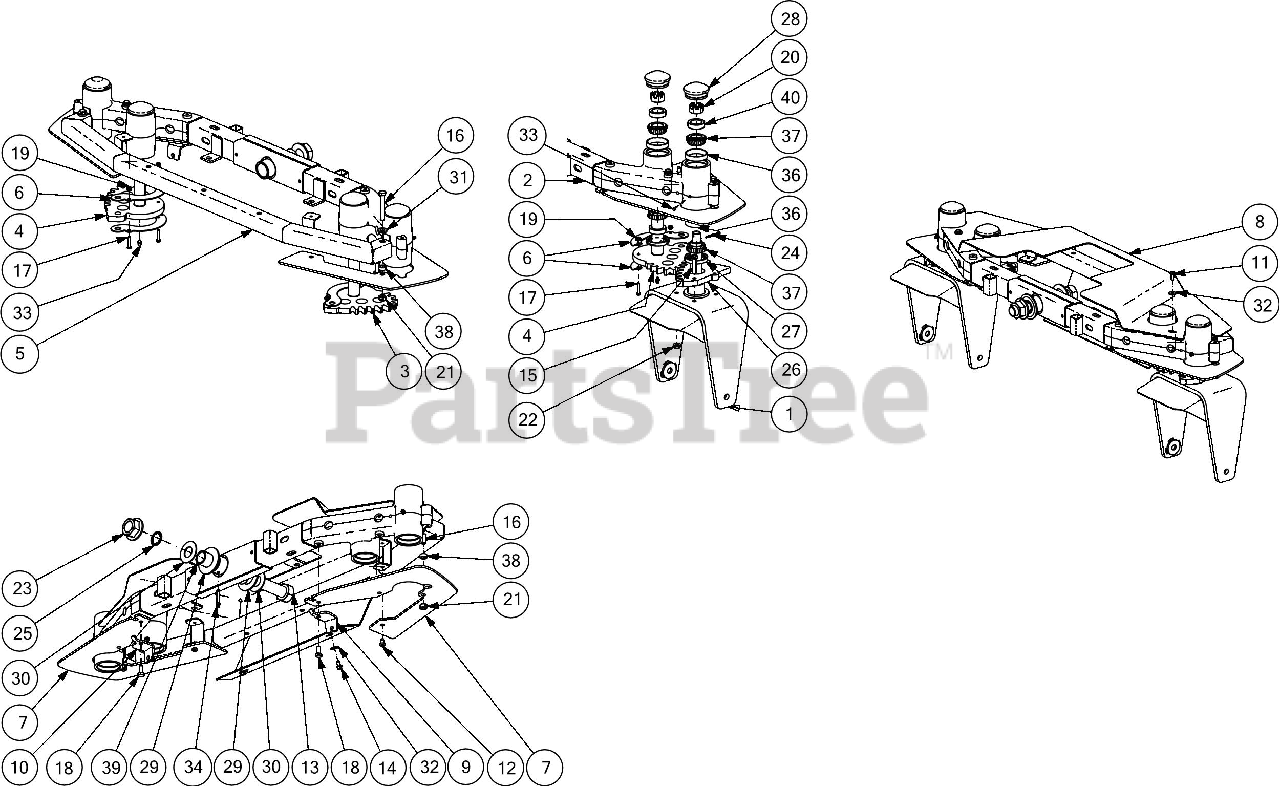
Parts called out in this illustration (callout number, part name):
1	TANK YOKE ASSEMBLY
2	AXLE ASSEMBLY
3	STEERING GEAR (LH)
4	STEERING GEAR (RH)
6	MOUNT BRACKET
7	GEAR PANEL COVER
9	CABLE MOUNT BRACKET (RH)
10	CABLE MOUNT BRACKET (LH)
11	SCREW 1/4-20 X .62 SPEC GR5
12	SCREW 1/4-20 X .5
13	SCREW 1-14 X 7.0 GR5
14	SCREW 1/4-20 X.500
15	SCREW 5/16-18 X 1.5 LG
16	HEX SCREW-3/8-16X2.5 GR5
17	SCREW #10-24 X 1.00 GR5.1
18	SCREW 5/16-18 X .750
20	HEX NUT CASTLE 3/4-16
23	HEX FLANGE NUT
24	COTTER PIN-5/32 DIA
25	RETAINING RING
26	STEERING GEAR YOKE
28	AXLE GREASE CAP
29	BELL WASHER 1.25ID X 2.5 X .180
30	FLAT WASHER 1.0 X 2.0 X .075
31	FLAT WASHER
32	FLAT WASHER
33	GREASE ZERT 1/4-28
34	GREASE FITTING
36	BEARING CUP
37	BEARING CONE
38	SPACER-.380 ID X .625 OD X .265
